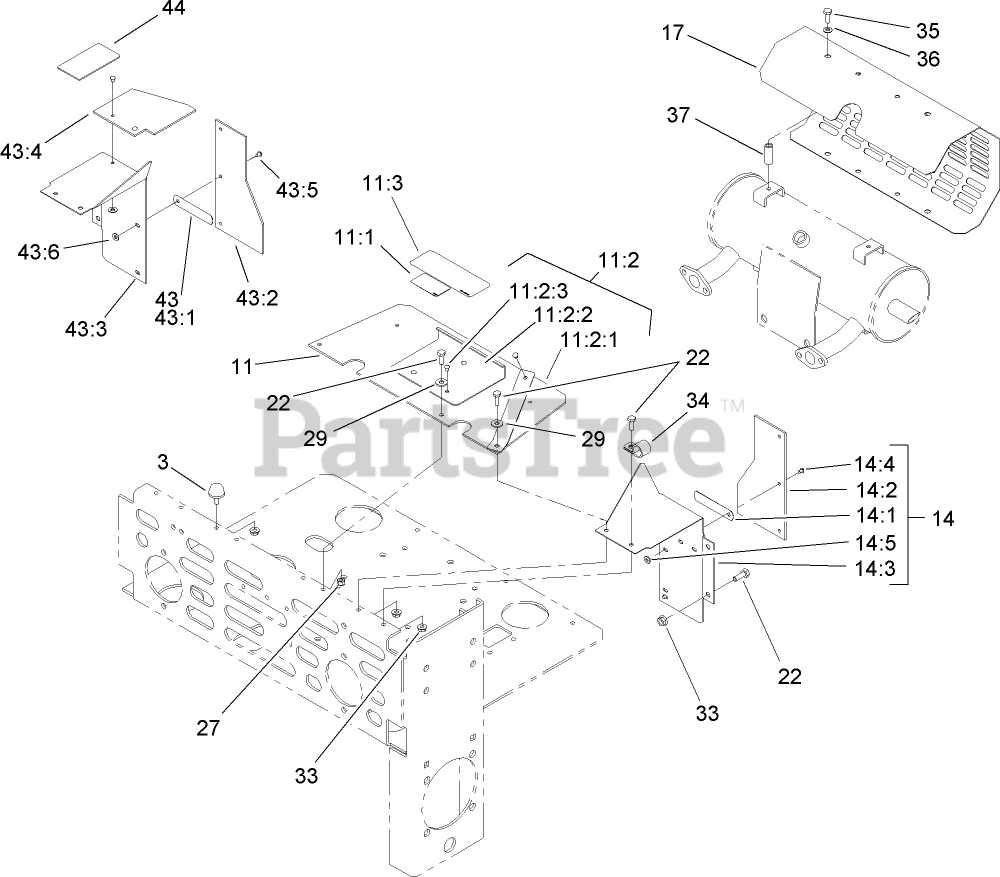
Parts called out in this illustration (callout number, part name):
3	BUMPER
11	SHIELD ASM
11:1	DECAL-IMPORTANT
11:2	SHIELD AND LIFT ASM
11:2:1	SHIELD-ENGINE
11:2:2	LIFT-SHIELD
11:2:3	RIVET-POP
11:3	DECAL-DEVICES, ROTATING
14	LH SHIELD ASM
14:1	CLIP-BAFFLE, REAR
14:2	SHIELD-ENGINE
14:3	BAFFLE-ENGINE SHIELD, LH
14:4	RIVET-POP
14:5	WASHER-FLAT
17	GUARD-MUFFLER
22	SCREW-HH
27	NUT-LOCK, NI
29	WASHER-FLAT
33	NUT-HF
34	CLIP-LOOM
36	WASHER-SPRING
37	SPACER
43	RH SHIELD ASM
43:1	CLIP-BAFFLE, REAR
43:2	SHIELD-ENGINE
43:3	SHIELD-RH
43:4	BAFFLE-COOLER, ENGINE
43:5	RIVET-POP
43:6	WASHER-FLAT
44	DECAL-ROUTING, BELT
